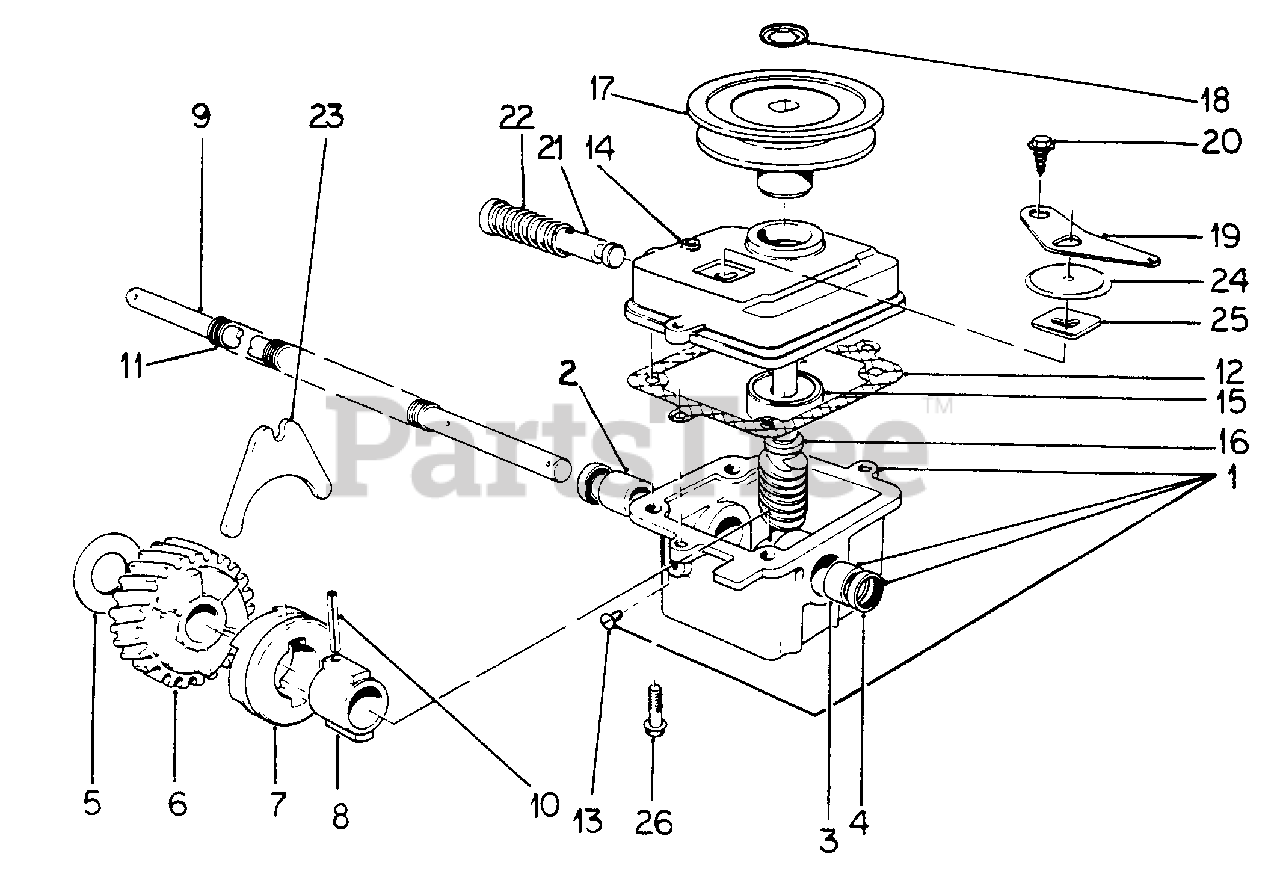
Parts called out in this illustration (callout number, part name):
1	CASE ASSY, GEAR
5	WASHER, THRUST
6	GEAR, HELICAL
7	CLUTCH, JAW
9	ROD, DRIVE
10	PIN, 1/8 X 3/4 HVY CLD-SPR
11	HOSE, DRIVE SHAFT
13	SCREW, 1/4-20 X 3/8 SHW NYLON
14	COVER, GEAR CASE
15	BEARING, BALL
16	SHAFT, WORM
17	PULLEY, DRIVEN
18	RING, RETAINING
19	ARM, SHIFTER
20	SCREW, NO.10 X 1/2 H/WHD TAP
21	PIN, SHIFTER
23	FORK, SHIFTER
25	PLATE, LATCH
